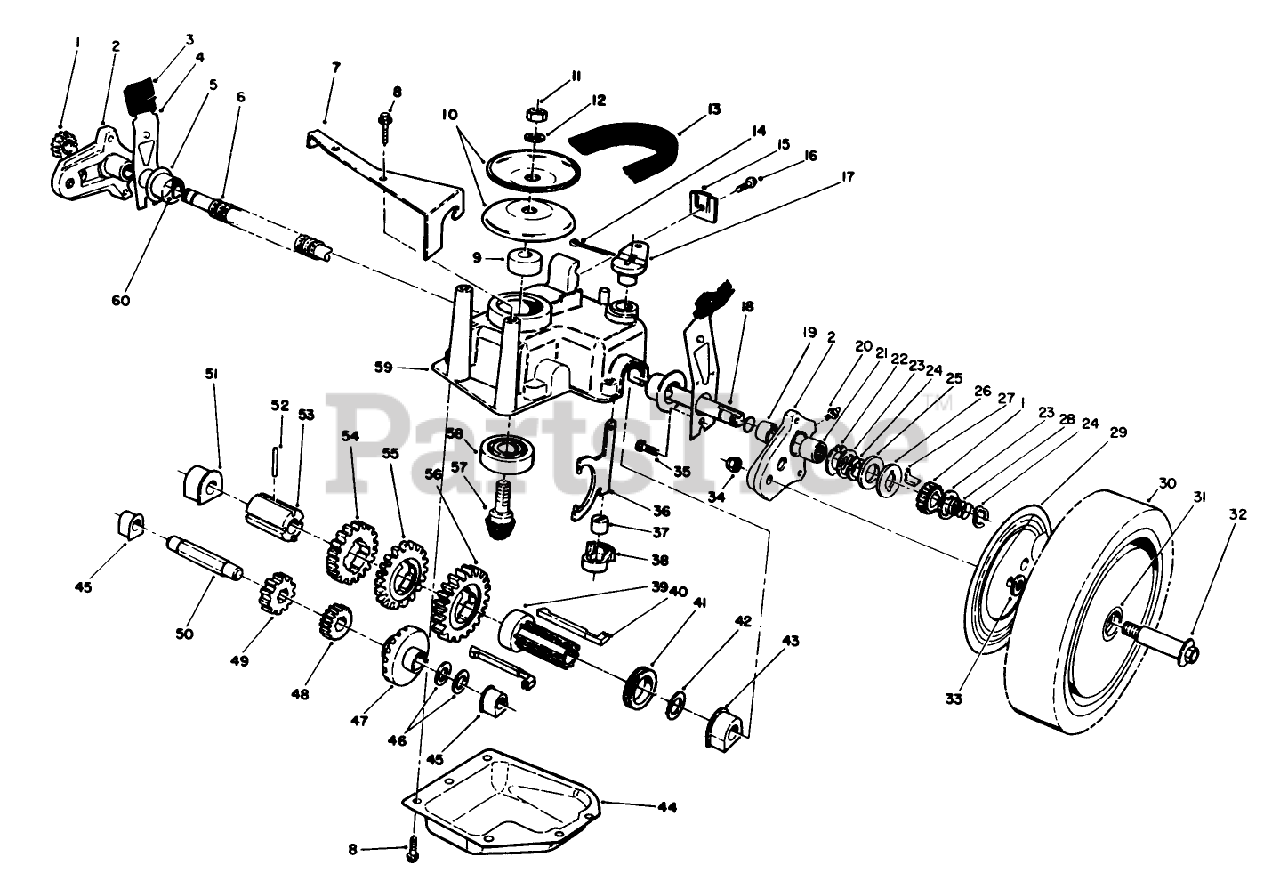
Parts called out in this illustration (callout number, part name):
1	Pinion
3	KNOB-ARM
4	SPRING ARM ASM SP
5	CAP-END
6	CONDUIT-CONVOLUTED, SPLIT
8	SCREW-HWHTF
9	SPACER
11	NUT-HEX
12	WASHER-FLAT
13	V-BELT
14	PIN-COTTER
16	SCREW-HWHTF
17	SHIFT LEVER
18	SHAFT-OUTPUT
19	BUSHING
20	FITTING-GREASE
22	Thrust Washer
23	Thrust Washer
24	RING-RETAINING,CLIP
25	RING-FRICTION
26	WASHER-CLUTCH
27	KEY-ROCKING, LH
28	SPRING-COMPRESSION
29	WHEEL COVER (BLACK)
31	HOC ADJUSTMENT ASM
32	WHEEL BOLT
33	WASHER
35	SCREW-HWH
36	YOKE-SHIFT
37	BUSHING-YOKE
38	RETAINER-FORK, SHIFT
42	WASHER-PLAIN
43	BUSHING-OUTPUT
45	BUSHING
46	WASHER-THRUST
47	Gear-Pinion 15 Tooth
48	PINION-20T
49	PINION-25T
51	BUSHING
52	PIN-SPRING
53	SLEEVE-GEAR
54	GEAR-39T
55	GEAR-44T
56	GEAR-49T
58	BEARING-BALL
59	CASE-GEAR, UPPER
60	O-RING
